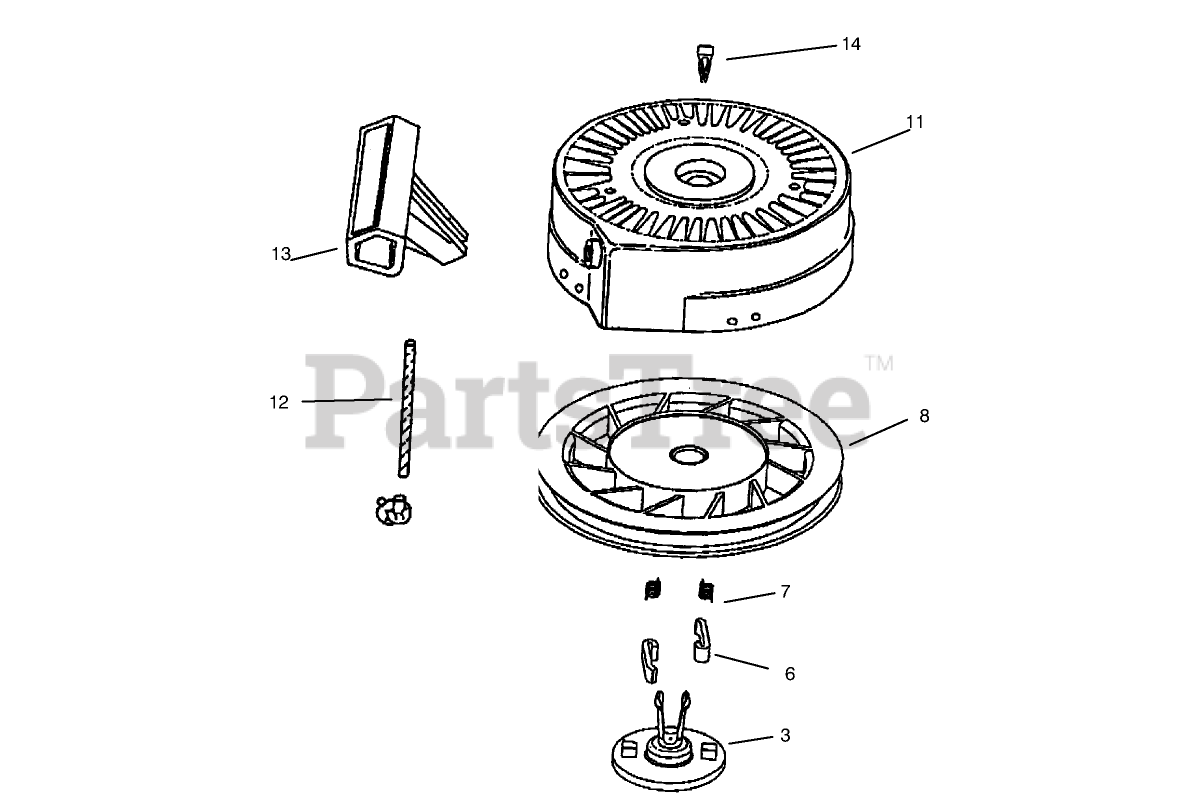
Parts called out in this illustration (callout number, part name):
3	Retainer
6	Dog-Starter
7	Spring-Dog
8	Pulley and Rewind Spring ASM
11	Starter Housing ASM
12	Rope-Starter (98 cut to length)
13	Handle-Starter (STD)
14	Locking Tab
